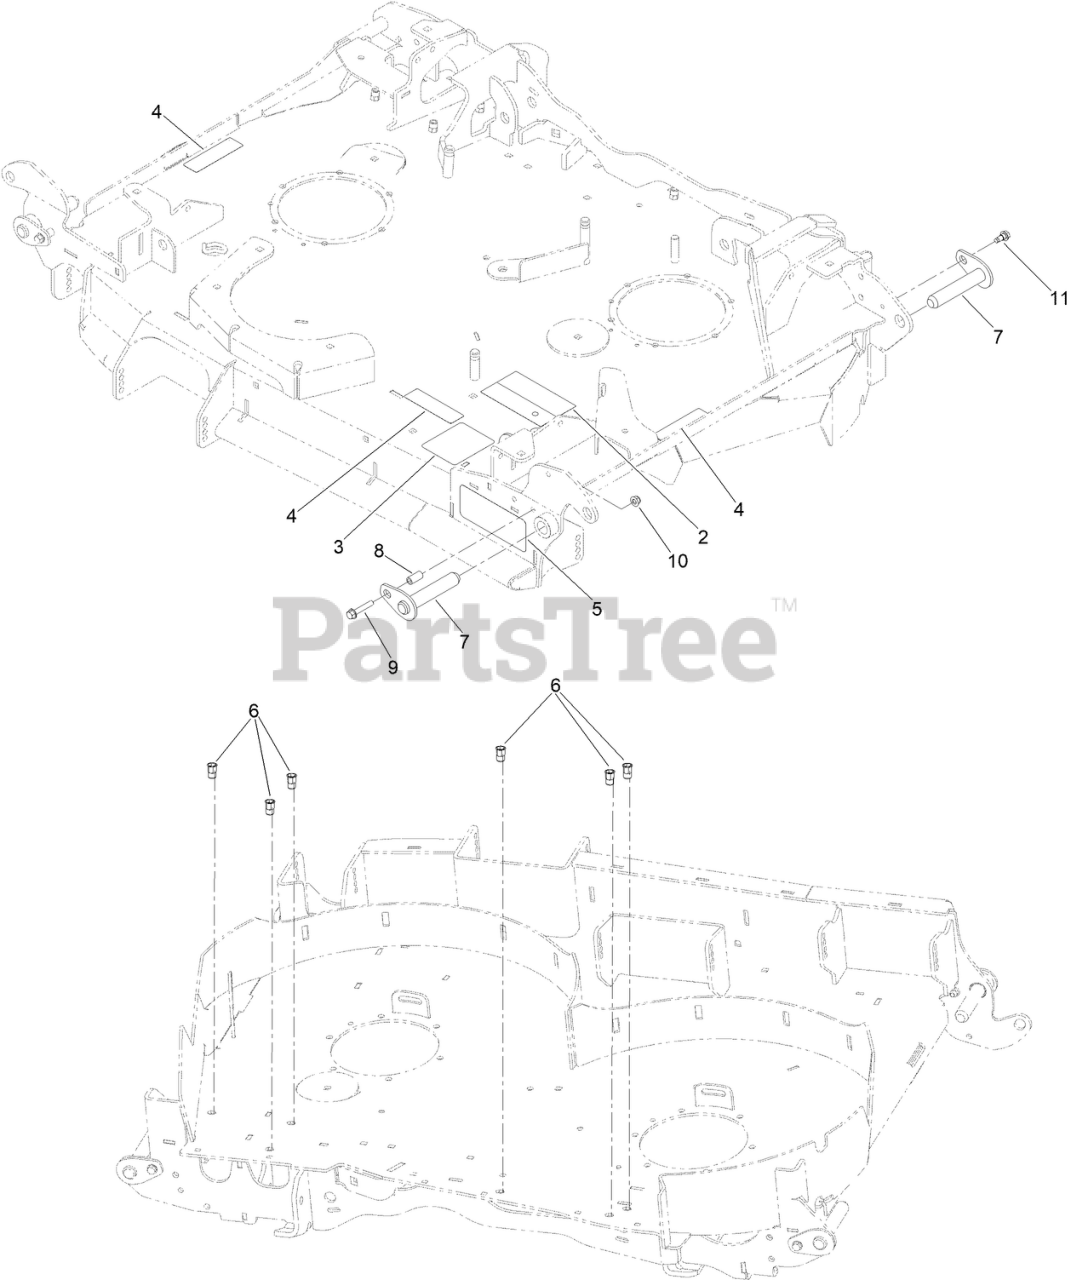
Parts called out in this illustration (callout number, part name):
2	DECAL-DECK BELT ROUTING
3	DECAL-ROLLER, ANTI-SCALP
4	DECAL-COVER, MISSING
6	NUT-CLINCH,HEX
7	ASM-DECK PIN
8	TUBE-STANDOFF
9	SCREW-HWH
10	NUT-HF, NI
11	SCREW-SHOULDER
